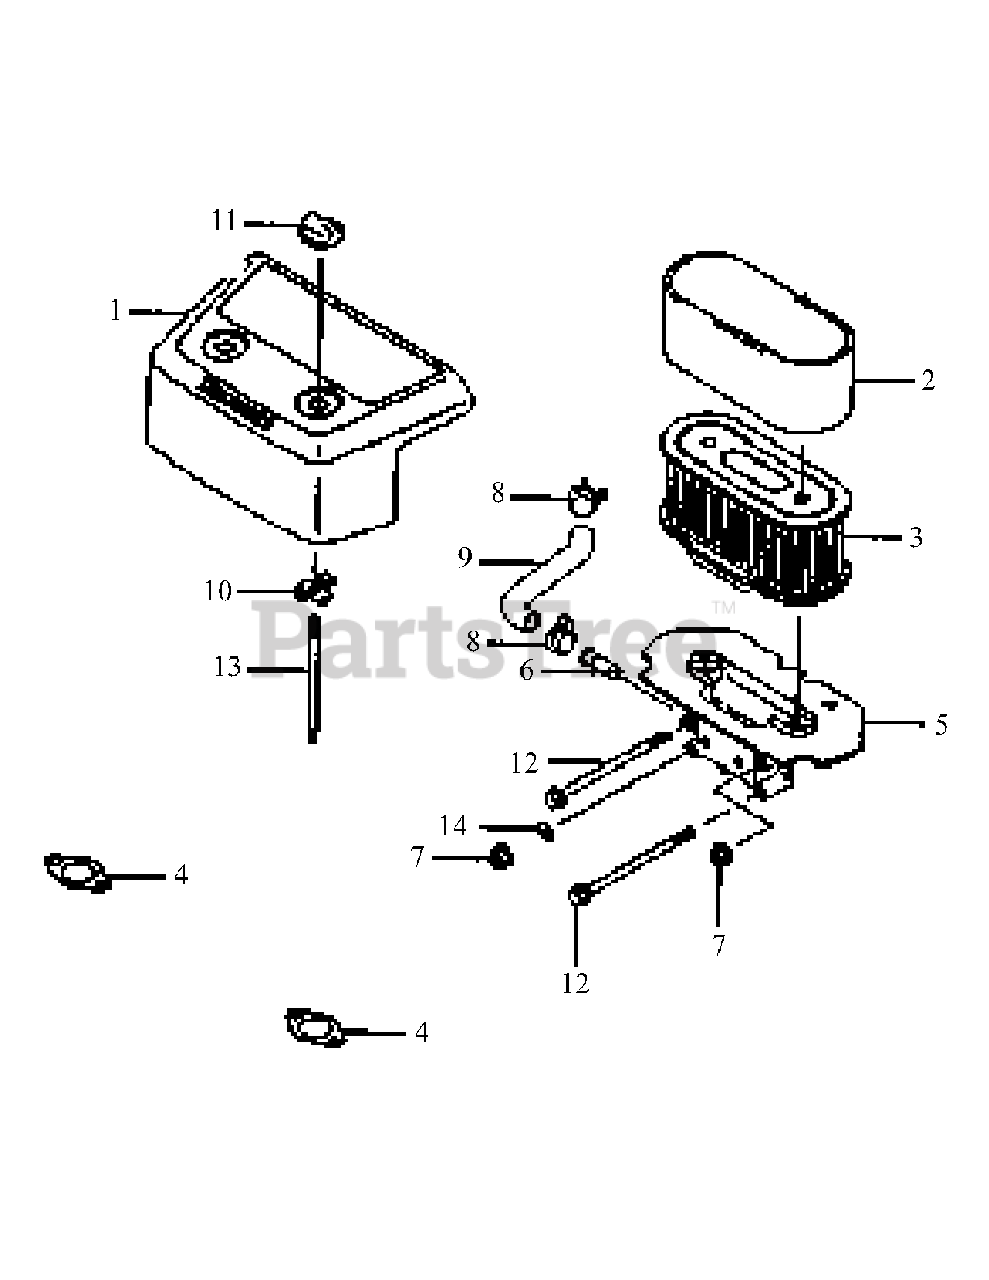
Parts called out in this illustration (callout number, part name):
1	Case-Air Cleaner
2	Element, Pre Filter
3	Element, Air Cleaner
4	Gasket-Muffler
8	Clamp
14	Washer-Plain
